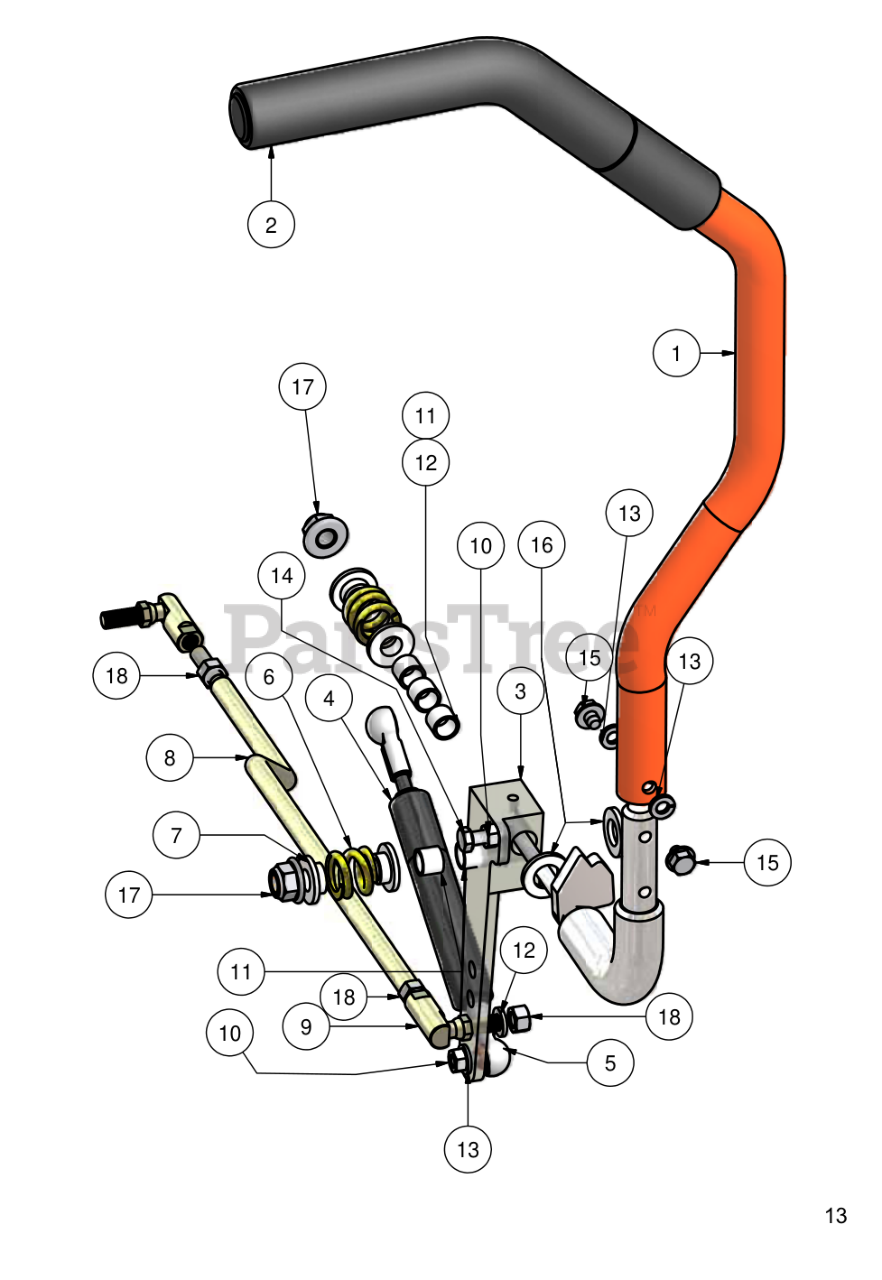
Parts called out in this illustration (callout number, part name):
1	Right Drive Arm
1	Left Drive Arm
2	Rubber Steering Handle
3	Left Drive Arm Lever Housing
3	Right Drive Arm Lever Housing
5	10MM Damper Ball Stud
6	Drive Lever Spring
7	.515 ID Nylon Shoulder Washer
9	3/8-24 Ball joint (female/male)
11	.507 ID Nylon Bushing
12	3/8" Lock Washer
13	5/16" Lock Washer
14	5/16" x 3/4" Hex Bolt
15	5/16" x 1/2" Flange Bolt
16	.505 ID Plastic Washer
17	1/2" Flange Lock Nut
18	3/8" Fine Thread Nut
